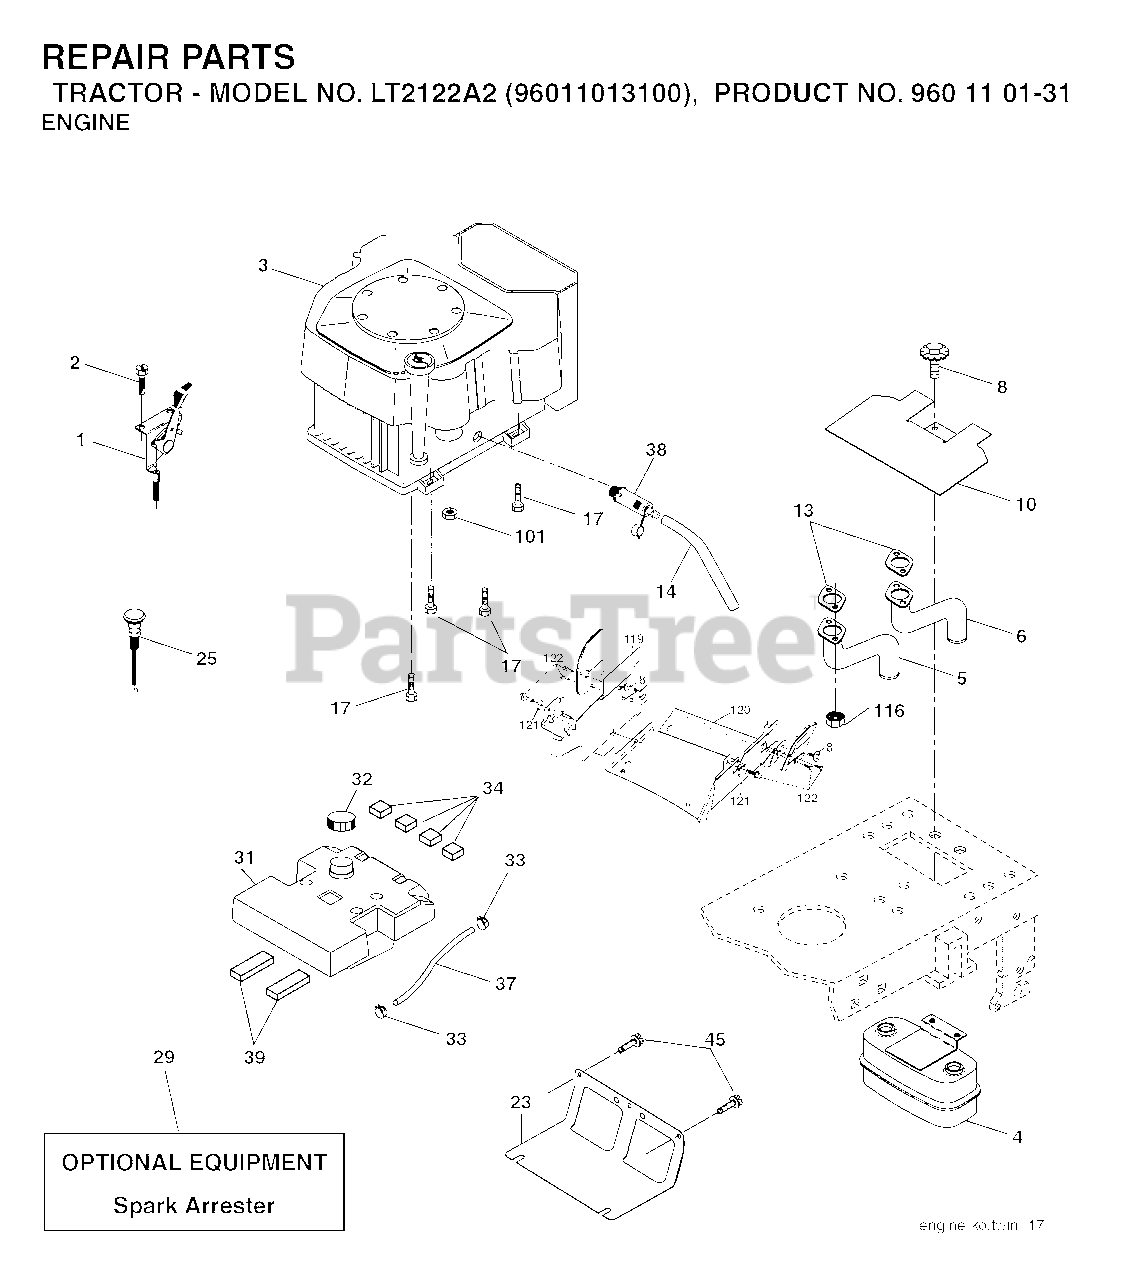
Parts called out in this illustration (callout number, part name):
1	CONTROL.THROTTLE.KAWA
2	SCREW
4	MUFFLER.TWIN.CYL.LOW.TONE
5	PIPE-EXHAUST LH
6	PIPE-EXHAUST RH
8	BOLT, 5/16-18 X 1 3/4
10	RP SHIELD HEAT MUFFLER
14	TUBE, DRAIN OIL ASM.
23	SHEILD.BROWNING.DBR.GUARD
25	CONTROL, CHOKE
29	ARRESTER SPARK (OPTIONAL)
31	TANK.FUEL(3.5.GAL)
32	FUEL CAP
33	HOSE CLAMP
34	PAD-SPACER LT
38	PLUG DRAIN OIL EASY
39	PAD IDLER TI
45	SCREW, 3/8-16X3/4
101	FLANGE NUT
116	NUT.HEX.FLANGE.TOPLOCK
122	SCREW.1/4-20X5/8
